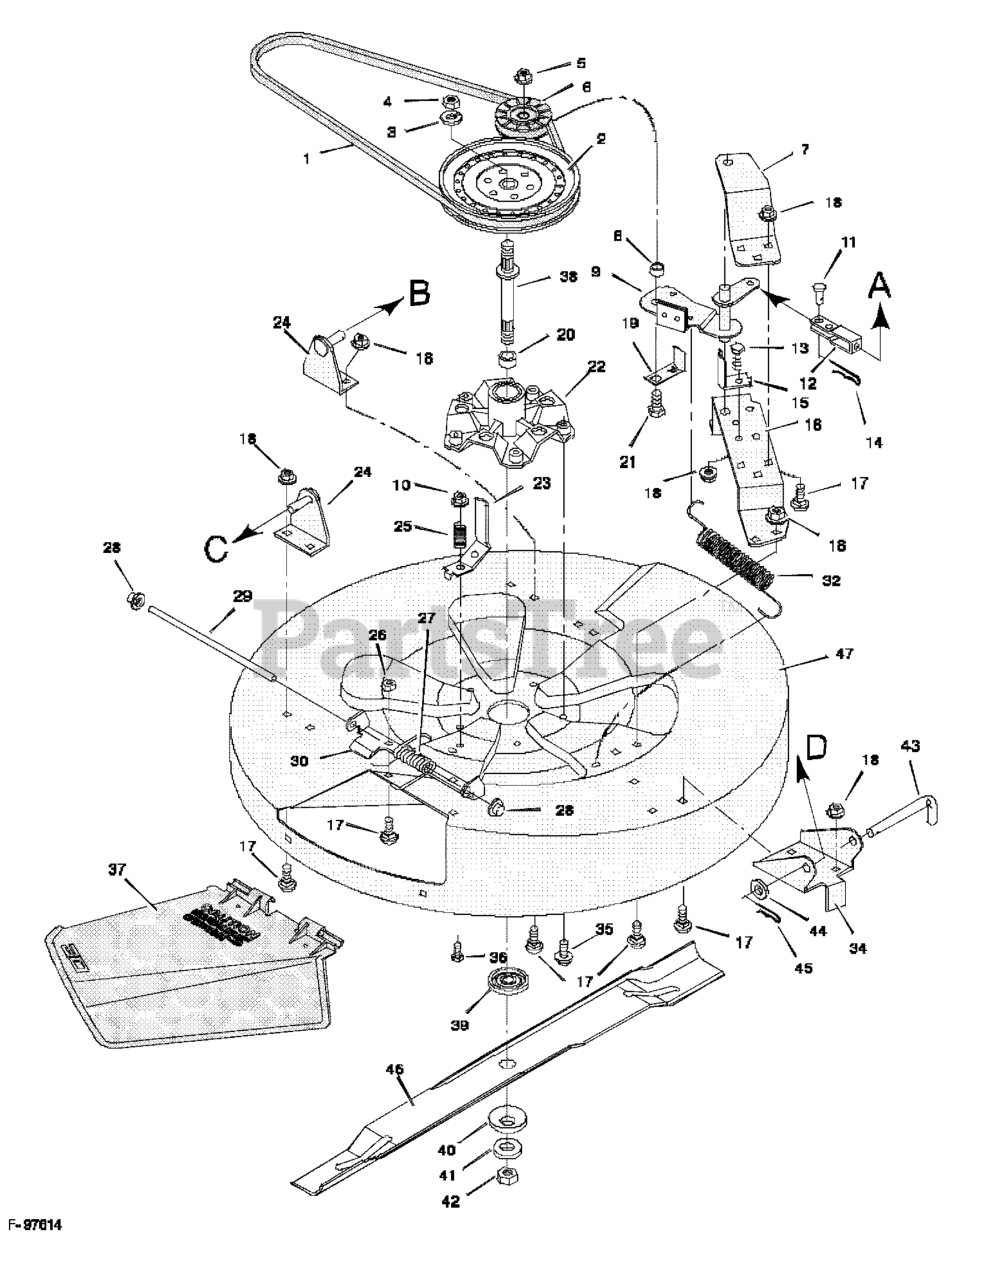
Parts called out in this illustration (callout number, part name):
1	Belt, Mower Drive
2	Pulley, Splined
3	Lockwasher
4	Locknut, Hex
5	Nut, Hex
6	Pulley, Idler
7	Bracket, Upper Idler
9	Assembly, Blade Idler
10	Locknut, Flange
11	Pin, Clevis
13	Bolt, Hex
14	Pin, Hair
15	Guide, Belt
16	Bracket, Lower Idler
17	Bolt, Carriage
18	Nut, Flange
19	Guide, Belt
21	Bolt, Hex
22	Housing, Mandrel
23	Guide, Belt
24	Bracket, Hanger
25	Spring, Compression
26	Nut, Hex
27	Spring - Torsional
28	Push On Cap
30	Hinge, Chute Deflector
32	Spring, Extension
34	Bracket, Front
36	Bolt, Hex
37	Deflector, Chute
38	Mandrel
39	Adapter, Blade
40	Washer, Belleville
41	Washer, Hardened
42	Nut, Hex
43	Pin, Pull
45	Pin, Hair
46	Blade, Standard
